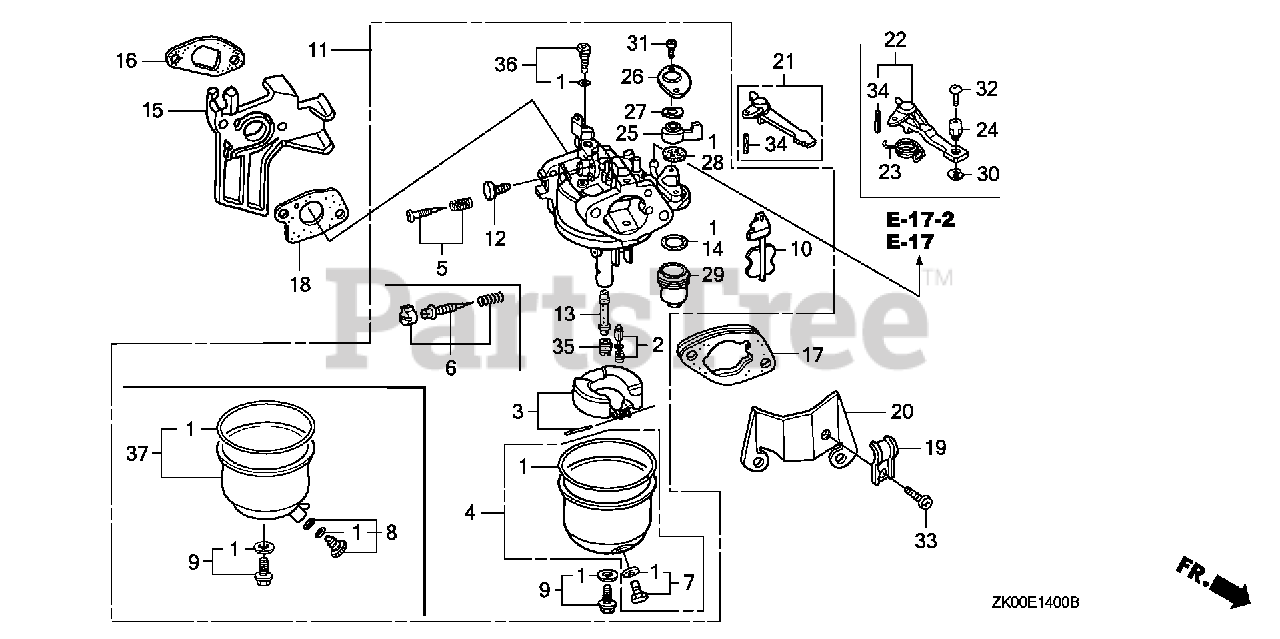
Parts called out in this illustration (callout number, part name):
1	GASKET SET
2	VALVE SET, FLOAT (SEAT NOT INCLUDED)
4	CHAMBER SET, FLOAT
6	SCREW SET, PILOT
7	SCREW SET, DRAIN
9	SCREW SET
11	CARBURETOR ASSY. (BE64B B/C)
12	SCREW, THROTTLE STOP
13	NOZZLE, MAIN
14	GASKET, FUEL STRAINER CUP
15	INSULATOR, CARBURETOR
16	GASKET, INSULATOR
17	SPACER, CARBURETOR
18	GASKET, CARBURETOR
21	LEVER, CHOKE (STD)
25	LEVER, PETCOCK
26	PLATE, LEVER SETTING
27	SPRING, PETCOCK LEVER
28	GASKET, PETCOCK
29	CUP, FUEL STRAINER
31	SCREW, PAN (3X6)
34	PIN, SPRING (2X12)
35	JET, MAIN (#72) (CARBURETOR NO.)
35	JET, MAIN (#68)
35	JET, MAIN (#70)
36	JET SET, PILOT (#45)
